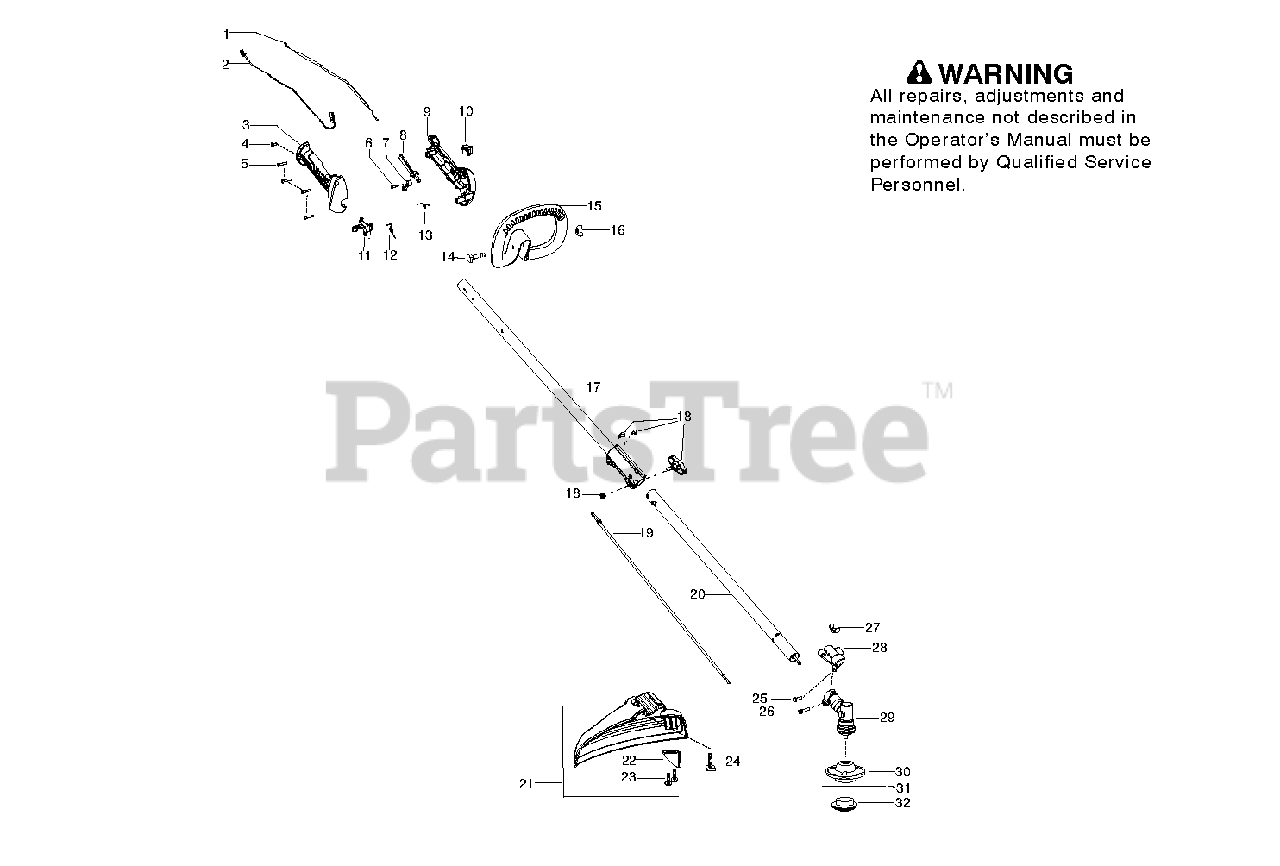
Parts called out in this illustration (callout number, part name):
2	SWITCH WIRE ASSY
3	THROTTLE HOUSING (RH)
7	ARM LOCKOUT
9	THROTTLE HOUSING (LH)
11	TRIGGER
12	TRIGGER SPRING
14	BOLT 1/4-20 X 2 SQUARE
15	HANDLE ASSIST 1"
16	WINGNUT, TYPE 2
17	KIT
18	ASSY COUPLER BLACK
19	Flex Shaft
20	KIT SHAFT LOWER SST BLACK
21	KIT SHIELD DOM NO BLADE
22	LINE CUTTER
24	BOLT, TYPE 2
25	SCREW 8-16 X 9/16 (PLAS
26	SCREW - CARB. ADAPTOR
27	WINGNUT, TYPE 2
29	GEARBOX 1
30	ASSY FIXED LINE HEAD
31	LINE FOR WT3100.080" PP325.115
32	CAP FIXED LINE
